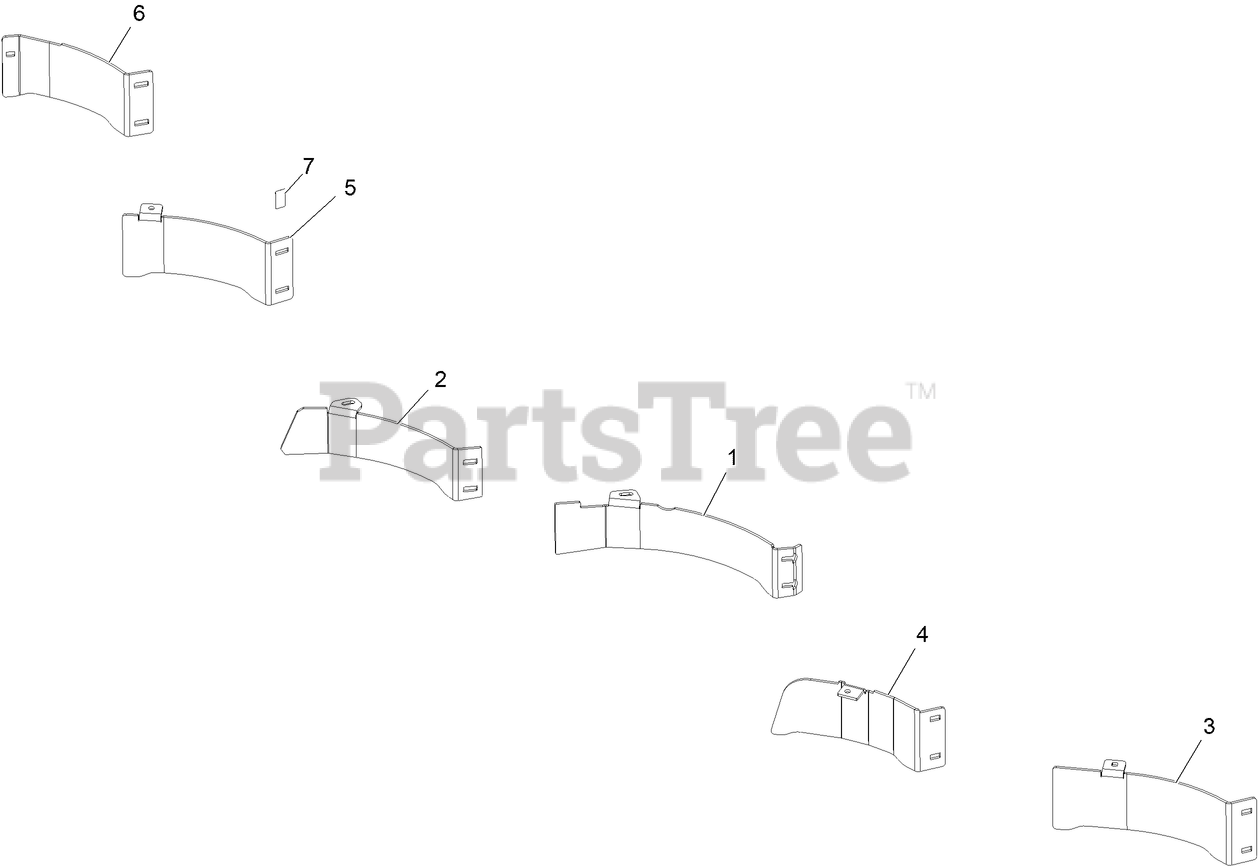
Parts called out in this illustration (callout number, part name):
1	BAFFLE-BLOCK, LH CTR
2	BAFFLE-BLOCK, RH CTR
3	BAFFLE-LH WING BLOCK
4	BAFFLE-MULCH, LH INSIDE
5	PLATE-MULCH
6	BAFFLE-WIDE OUTSIDE MULCH
7	Decal-Patent Ttco.Com
